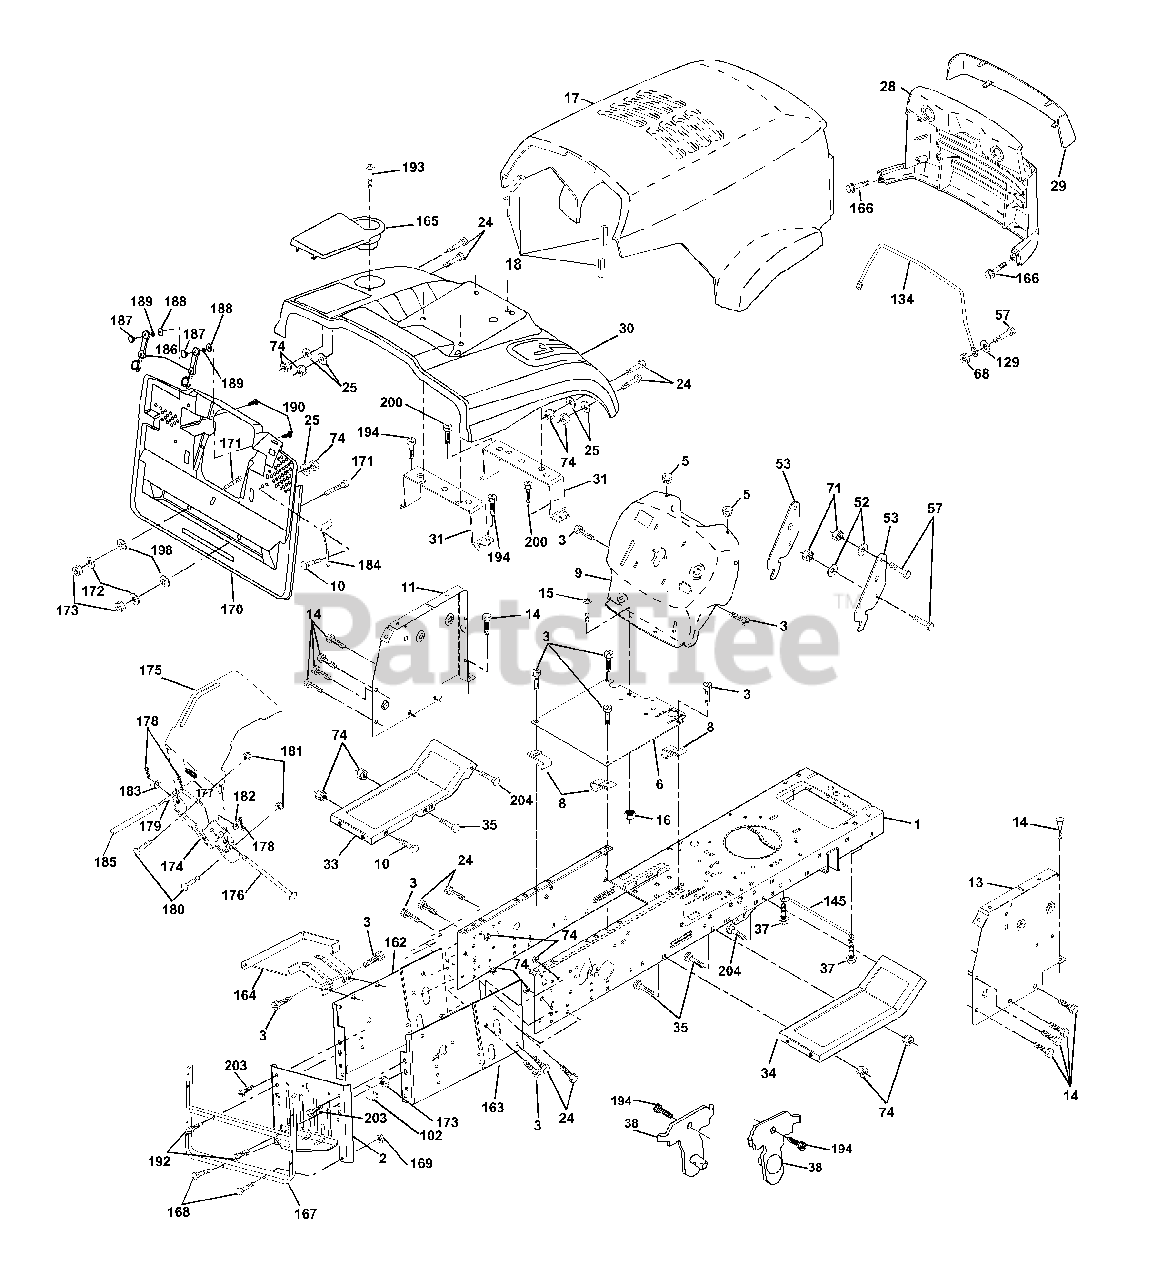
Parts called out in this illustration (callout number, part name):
1	Chassis Stamping
2	Drawbar, CRD
3	Screw Thdrol 3/8-16x3/4 Ty-tt
5	Bumper Hood/Dash
6	Saddle Flat Lt Fender Shift
8	Clip Insulator 13/32 Mtg Hole
10	Bolt Carriage 3/8-16 x 1
11	Panel Dash Lh
13	Panel Dash Rh
14	Screw Thdrol 3/8-16 x 1/2
15	Screw Mach Trhd 5/16-18 Unc x 3/4
16	Nut Keps 5/16-18 Unc
17	Hood Pnt
18	Bumper Hood
24	Bolt Fin Hex 3/8-16 Unc x 1 Gr 5
25	Washer 13/32 X 13/16 X 12 Ga
28	Grille
29	Lens
30	Fender
31	Bracket Support Fender
33	Footrest Pnt Lh
34	Footrest Pnt Rh
35	Bolt Rdhd Sht Sqnk 3/8-16 x 3/4
37	Screw Thdrol 5/16-18 x 1/2 TYT
38	Bracket, Asm. Pivot, Mower Rear
51	Nut Lock w/insert 1/4-20
52	Washer 9/32 x 7/8 x 16 Ga
53	Bracket Grille Pickoff LH
57	Bolt Fin Hex 1/4-20 Unc x .75
68	Nut Keps Hex 1/4-20 Unc
74	Nut
102	Clip Line Fuel 13/32 Mtg Hole
129	Washer 9/32 x 5/8 x 16 Ga.
134	Rod Support Hood Husq P/L
145	Rod Pivot Chassis/Hood
162	Bracket Exten Chassis Lh
163	Bracket Exten Chassis Rh
164	Support Battery CRD
165	Cover Battery CRD Lt Black
166	Screw Hwhd Hi-Lo #13-16 x 3/4
167	Support Asm Backplate Wldmnt
168	Bolt Rdhd Sht NK 1/4-20 x 1-1/2
169	Nut lock 1/4 Lge Flg Gr 5 Zinc
170	Cover Backplate Plastic Black
171	Bolt Hex 3/8-16 x 2-1/2
172	Washer 13/32 x 1-1/4 x 16 Ga
173	Nut Keps Hex 3/8-16 Unc
174	Bracket Switch FBI CRD
175	Guard Door Rear CRD
176	Pin Hinge Pivot
177	Spring Bagger Top Lh Black
178	Pin Cotter 3/32 x 3/4 Cad
179	Rod Pivot FBI CRD
180	Bolt Hex Hd 5/16-18 Unc x 1
181	Nut Crownlock 5/16-18
182	Washer .385 x .625 x 11 Ga
183	Washer 13/32 x 13/16 x 16 Ga
184	Bracket Actuator Bagger CRD
185	Tube Lever Swch FBI CRD 2-1/16
186	Latch Asm Mulch/Bagger
187	Nut Weld .327/.304 #10-24
188	Washer #10
189	Washer Lock #10
190	Screw Truss Hd Phil 10-24 x 5/8
192	Screw Thdrol 3/8-16 x 1-1/2
193	Screw Truss 1/4-20 x 3/4
194	Screw 3/8-16 x .75
203	Screw thdrol 3/8-16 x 3/4 Tytt
204	Screw Thdrol 3/8-16 x 3/4
